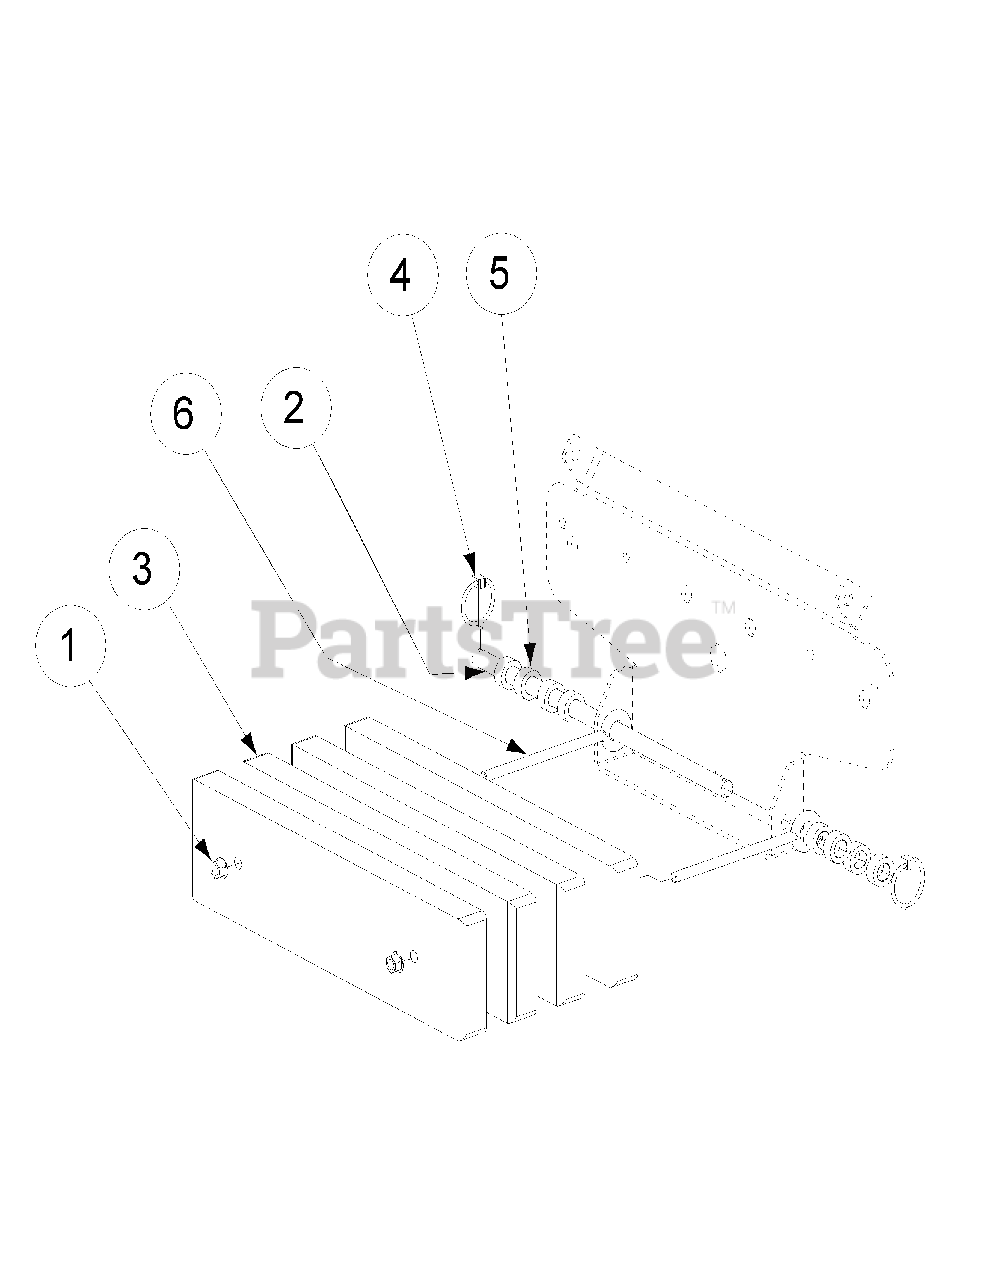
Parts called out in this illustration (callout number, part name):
1	Flange Lock Hex Nut, 3/8-16
2	Front Lift Link, Rod Mount
4	Linch Pin, 3/16 Dia.
5	Spacer, .630 x 1.06 x .440
6	Eyebolt, 3/8-16, Forged Steel
